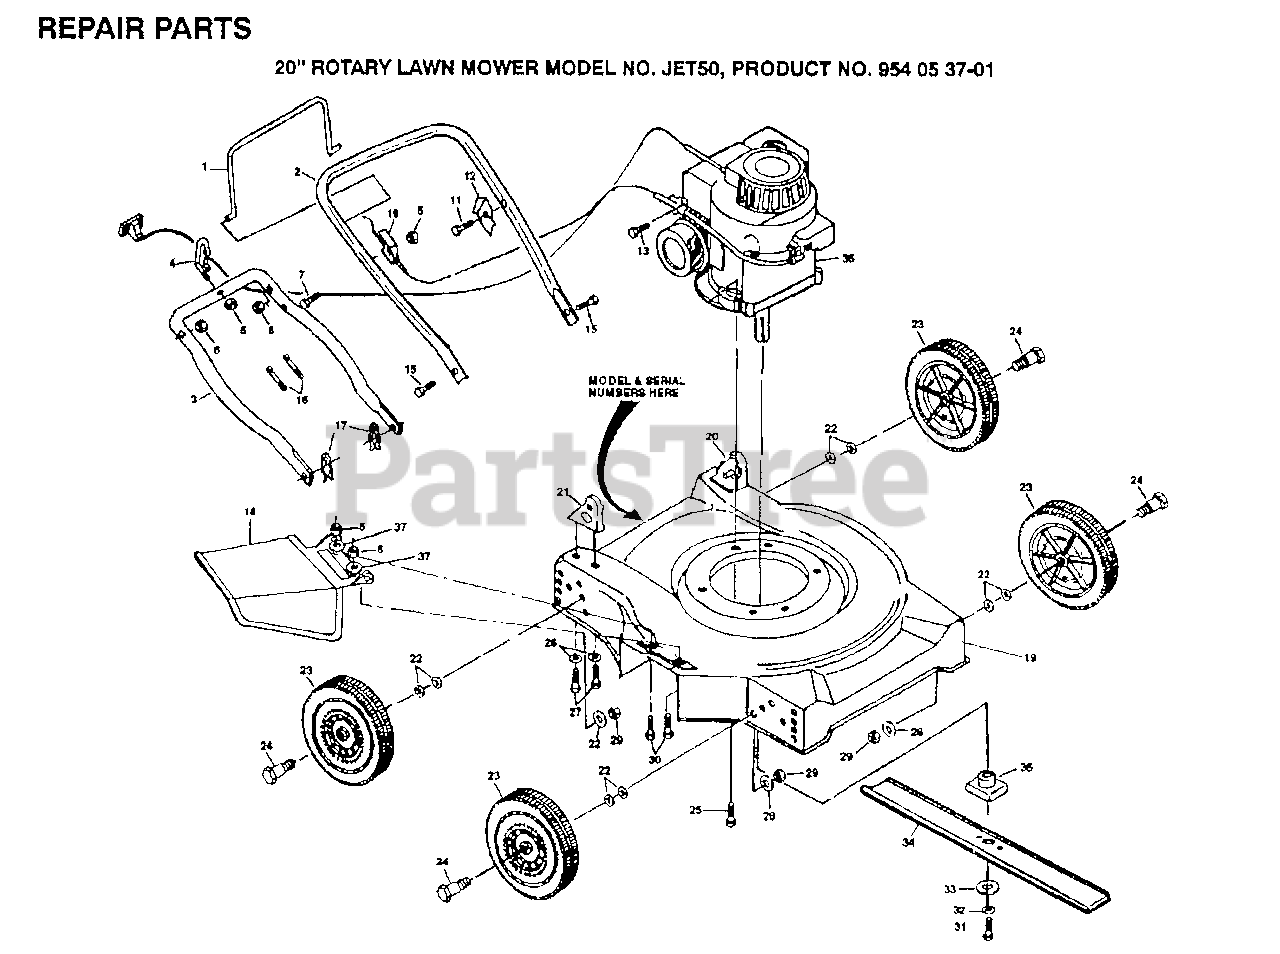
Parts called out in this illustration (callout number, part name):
1	Control Bar
2	Upper Handle
3	Lower Handle
4	Rope Guide
8	Washer
9	Spacer
10	Engine Zone Control Cable
12	Up-Stop Bracket
16	Wire Tie
17	Hairpin Cotter
18	Discharge Guard
19	Housing Assembly
20	Handle Bracket Assembly (Left)
21	Handle Bracket Assembly (Right)
22	Washer
23	Wheel & Tire Assembly 7.0 x 1-1/2
24	Shoulder Bolt
26	Washer
28	Washer
31	Hex Head Screw 3/8-24 x 1-3/8 Gr. 8
33	Hardened Washer
34	20" Blade
35	Blade Adapter
